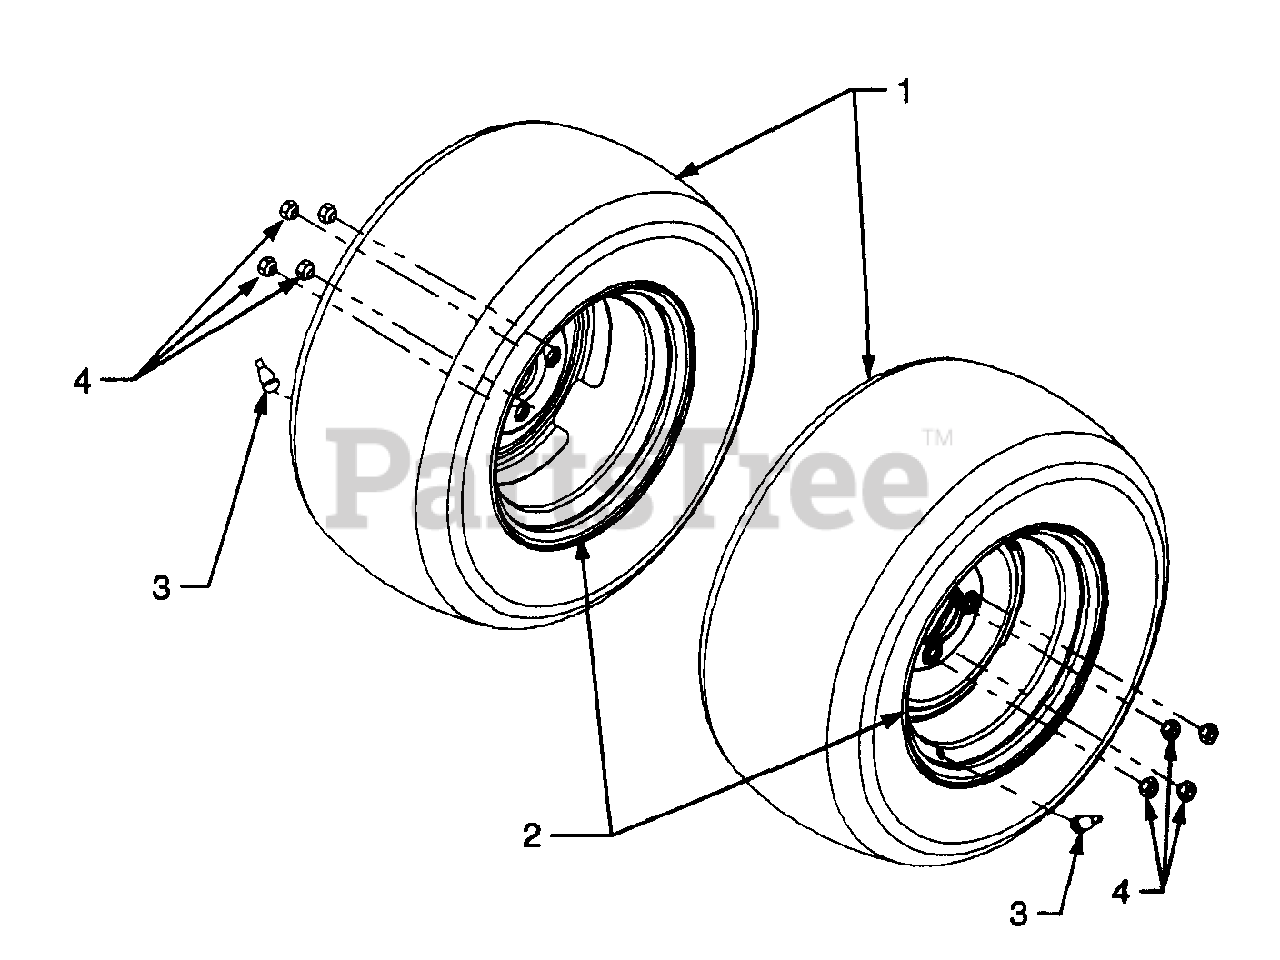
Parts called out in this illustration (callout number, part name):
1	Tire, Turf, 24 x 10.5 - 12
2	Rim Assembly, Wheel
3	Valve, Tubeless Air
4	Lug Nut, 7/16-14
